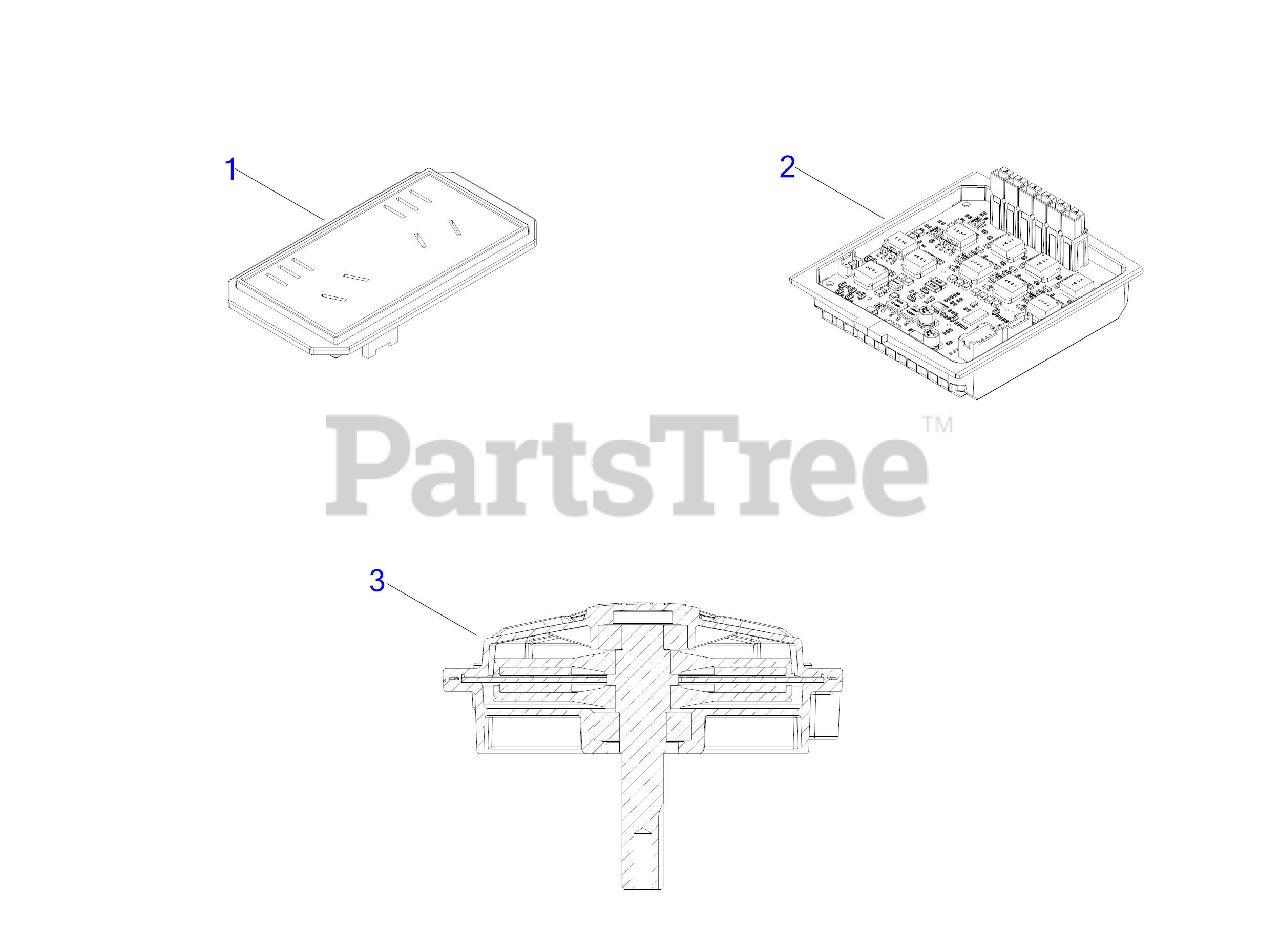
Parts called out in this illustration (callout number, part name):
1	OPERATORS PANEL ASSEMBLY
2	CONTROLLER ASSEMBLY CORE MOWER 700
3	MOTOR ASSEMBLY
